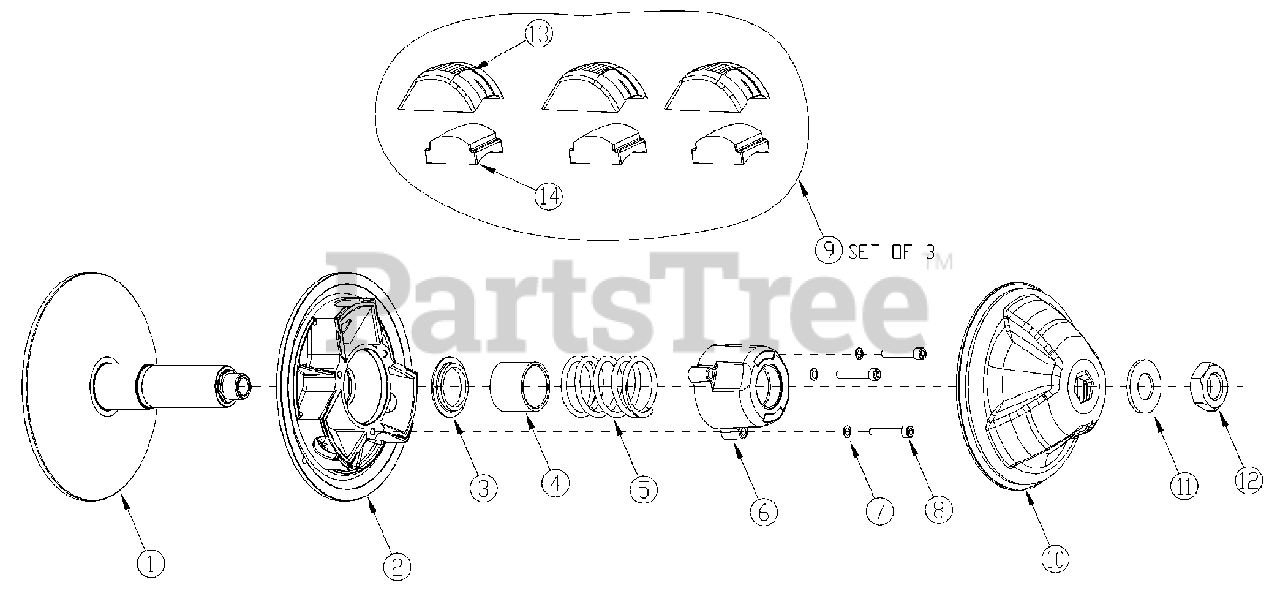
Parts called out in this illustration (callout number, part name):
1	FIXED FLANGE
2	SLIDING FLANGE
3	SPRING SUPPORT
4	STROKE LIMITER
5	SPRING
6	SPRING COVER
7	LOCK WASHER
8	SOCKET HEAD CAP SCREW
9	BLOCK ASSEMBLY
10	CAP
11	WASHER, FLAT #10 ZP SAE
12	NUT HEX 7/8-14 PLT
13	BLOCK
14	WEIGHT
